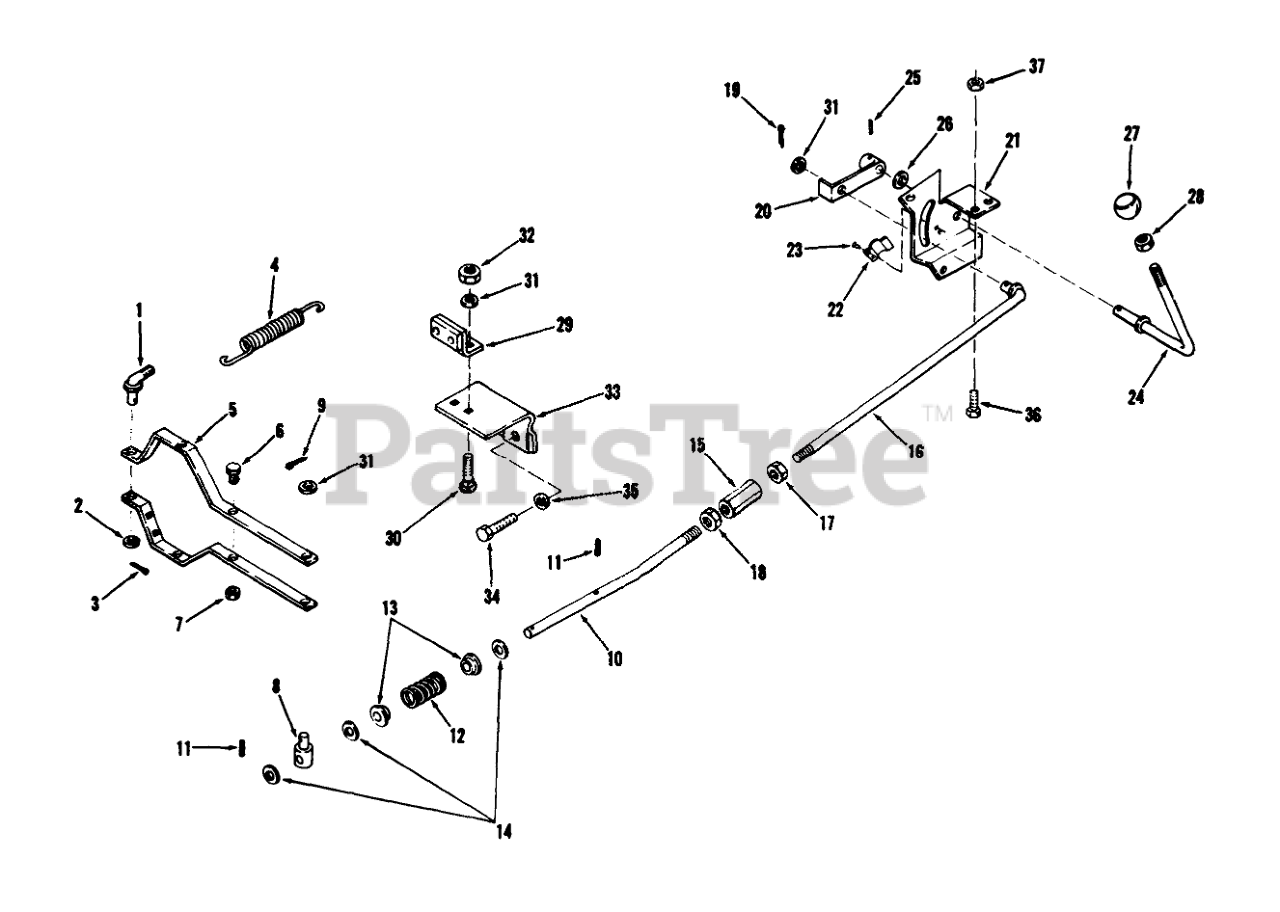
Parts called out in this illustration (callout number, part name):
1	ASSY HOOK
2	WASHER
3	Pop Rivet
4	CLUTCH SPRING
5	ASSY-CLUTCH BAR R
6	BOLT
7	Nut
8	TRUNION
10	CLUTCH ROD
11	PIN-ROLL
12	SPRING
13	Bushing
14	Washer
15	TURN BUCKLE NUT
16	Assy-Clutch Rod
17	Jam Nut
20	ARM CLUTCH ENGAGE
21	BRACKET
22	Clip Spring
23	RIVET -4
24	ASSY CLUTCH HANDLE
25	Spirol Pin
26	Washer
28	Jam Nut
29	Clutch Brake
30	Bolt 1/4-20 X 5/8
32	Nut
33	Bracket-Brake
35	LOCKWASHER
36	Bolt
37	Nut
